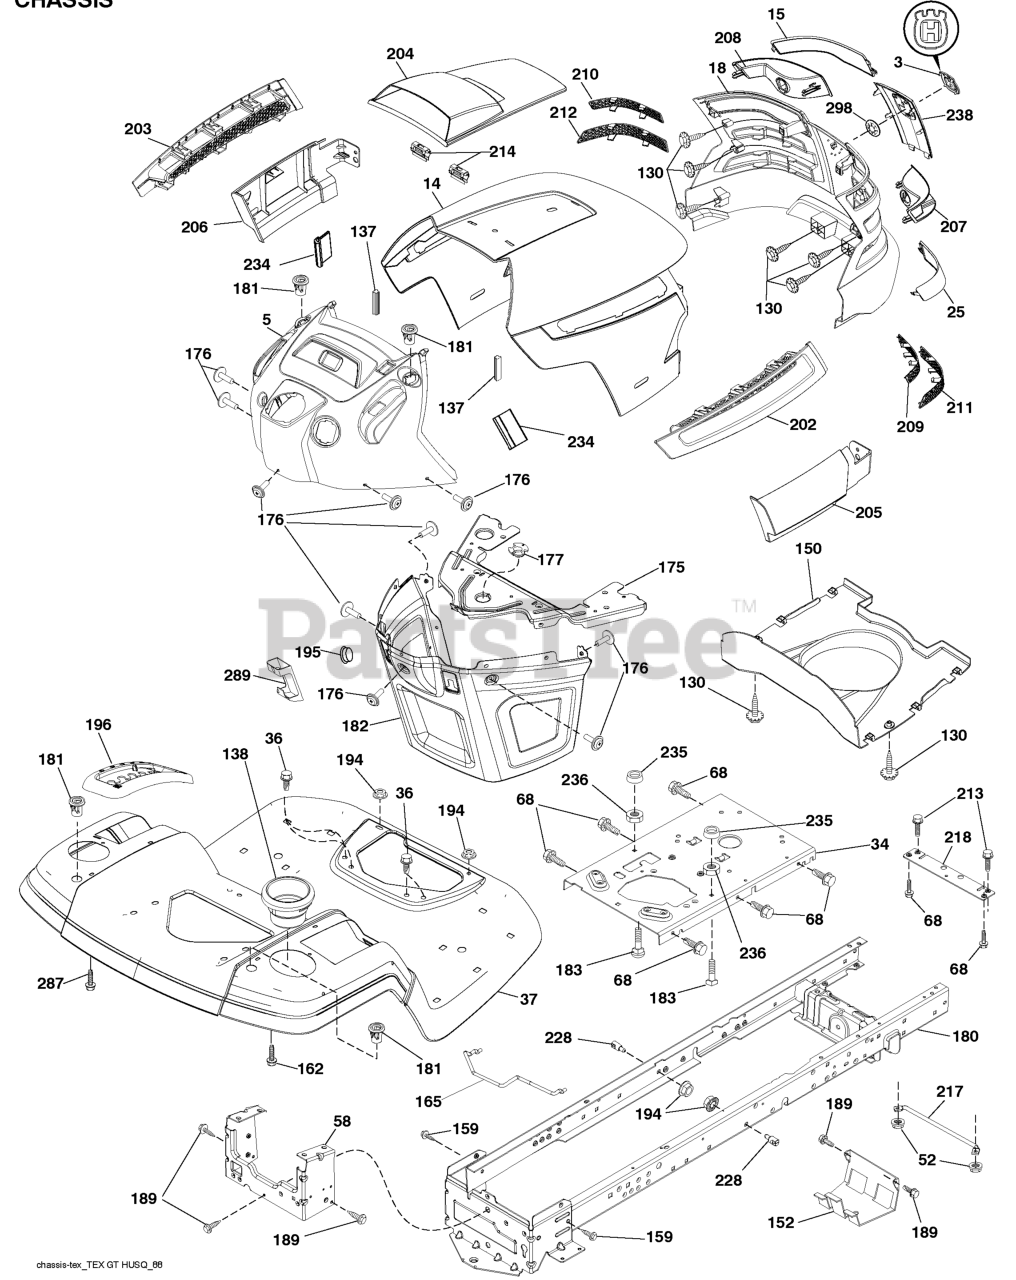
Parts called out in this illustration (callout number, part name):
3	RP LOGO
5	DASH.ASM.HUSQ.GT.CC.N/GA.N/C
14	HOOD
15	LENS.LH.TEX.GT.HUSQ.CL
18	GRILL.ASM.HUSQ.TG/CRD.W/TRIM
25	LENS.RH.TEX.GT.HUSQ.CL
34	PLATE.ENGINE.WELDED.CHASSIS
36	SCREW 5/16"
37	FENDER.TLT.FS.W/CPH/FW/RSF.ORN
52	LOCKNUT
58	DRAWBAR UPPER 2PC SMALL FENDER
68	Screw THDROL 5/16-18 x 1/2
130	SCREW.#10 X 0.750.BOS
137	BUMPER DASH
138	CUPHOLDER.TL.TEX.418
150	AIR.DUCT.TEXGT.HUSQ.31
152	SHIELD.BROWNING.W/TEX
159	SCREW, 3/8-16X3/4
162	SCREW.HI-LO.CONSOLE
165	SUPPORT.TANK.REAR.W/TEX
175	PLATE.CROSSMEMBER.HUSQ
176	SCREW.#10-24X5/8.RN.QU
177	BUSHING, STEERING
180	CHASS.WLDMNT.TL.12GA/2P.48/54
181	BUSHING.MNT.FEND.CRGO.
182	DASH.LOWER.COMMON.12V.ADAPTOR
183	BOLT.5/16-18X1-1/4 FULL THD
189	SCREW
194	NUT LOCK HEX FLANGE 5/16-18
195	PLUG.HOLE.DASH.LOWER.12V.BLK
196	RP CONSOLE.ASM.DECKLFT.GR/RBT.
202	VENT.SIDE.HOOD.HUSQ.RH.GREY
203	VENT.SIDE.HOOD.HUSQ.LH.GRAY
204	HOOD VENT
205	SKIRT.HOOD.SIDE.HUSQ.RH.GREY
206	SKIRT.HOOD.SIDE.HUSQ.LH.GREY
207	BEZEL.RH.TEX.GT.HUSQ
208	BEZEL.LH.TEX.GT.HUSQ
209	INSERT.HEX.GRILL.HUSQ.GREY
210	INSERT.HEX.GRILL.HUSQ.
211	INSERT.HEX.GRILL.HUSQ.
212	INSERT.HEX.GRILL.HUSQ.
213	BOLT
214	CLIP.RETAINER.TINNER.
217	ROD.PIVOT.HOOD
218	X-PIECE.HOOD.STOP.NON/
228	STUD.FASTNER.W/ANTI-ROTATE
234	BUMPER.HOOD.TEX.HUSQVARNA
235	SPACER FENDER
236	NUT.CENTERLOCK.5/16-
238	TRIM.HUSQ.TG/CRD.SERVICE
287	SCREW 1/4X20
289	PLUG.N/CRUISE.COMMON.YT/GT.BLK
298	NUT PUSH M
